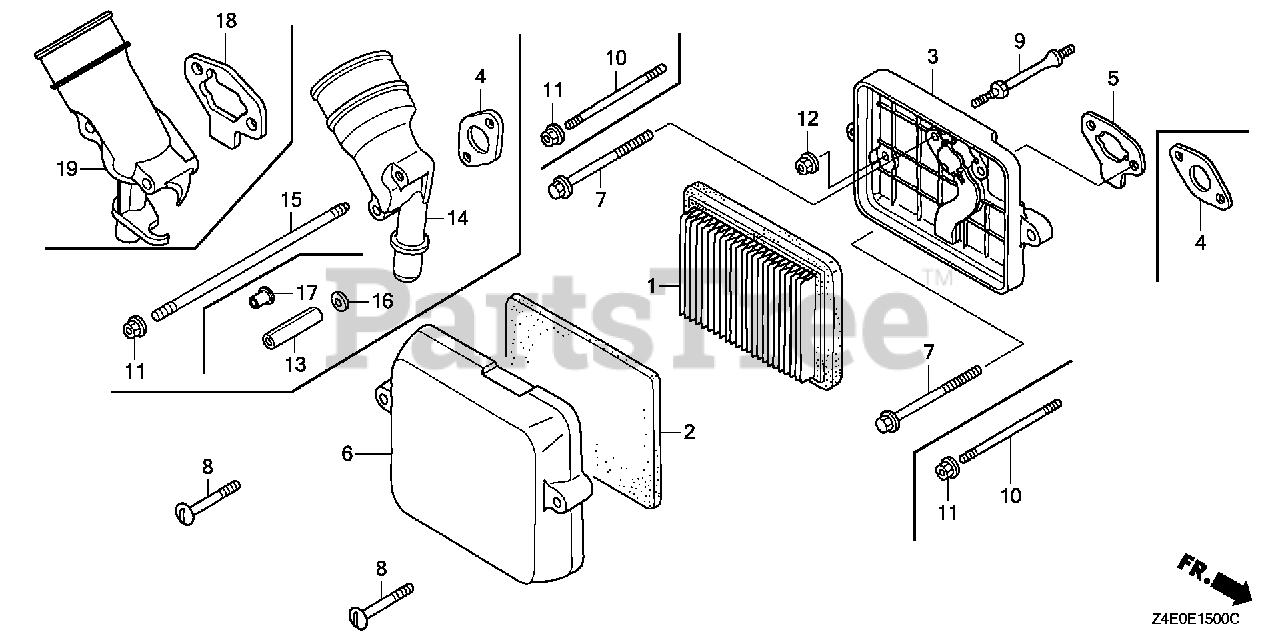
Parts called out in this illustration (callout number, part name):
1	ELEMENT, AIR CLEANER (TOYO ROKI)
3	HOUSING, AIR CLEANER
4	GASKET, AIR CLEANER
6	COVER, AIR CLEANER
8	BOLT, AIR CLEANER COVER
9	BOLT, STUD
10	BOLT, STUD (5X85) (CT200)
10	BOLT, STUD (5X88) (CT200)
11	NUT, FLANGE (5MM)
12	NUT, FLANGE (6MM)
